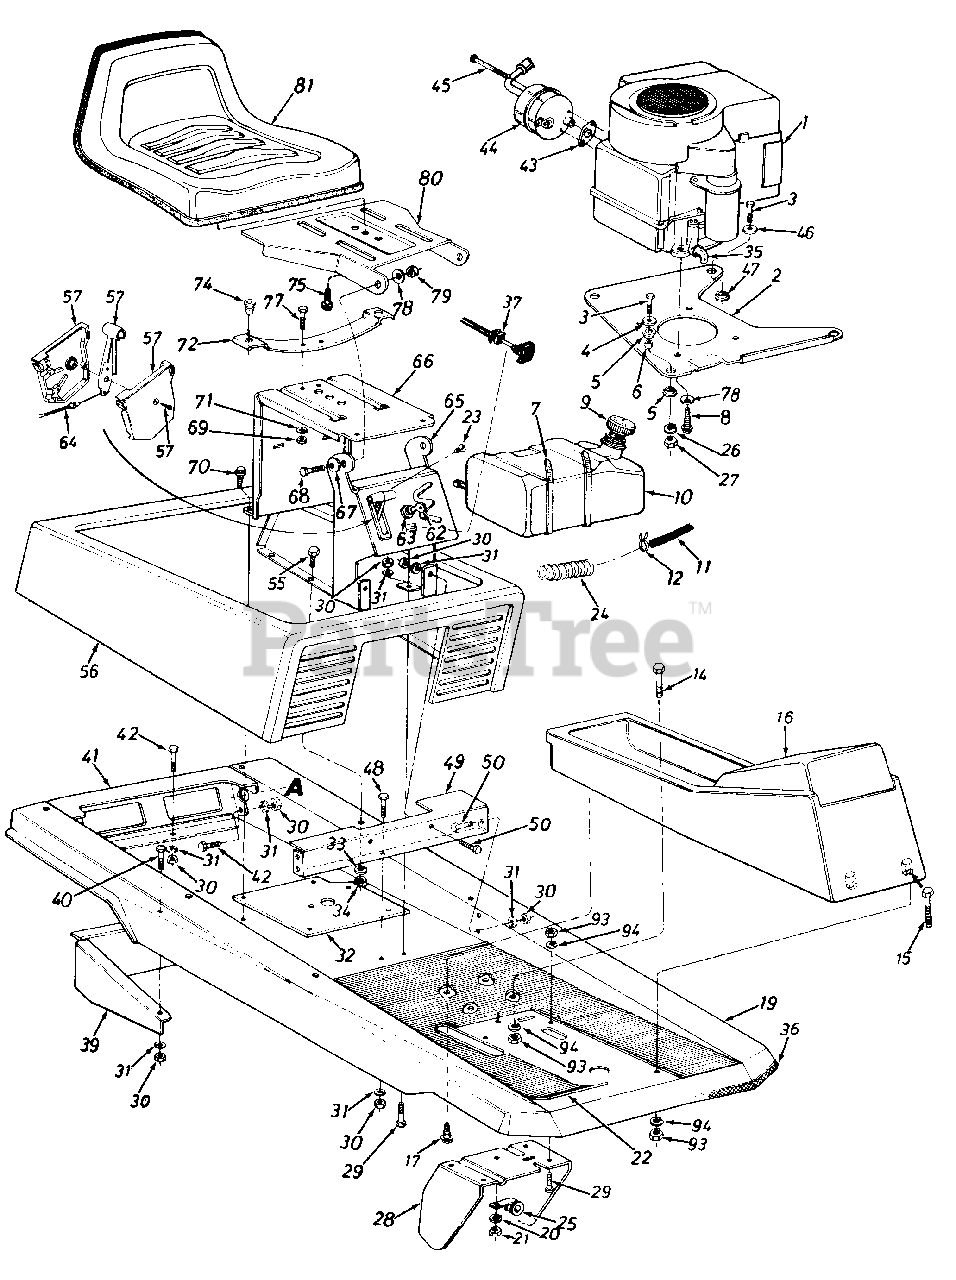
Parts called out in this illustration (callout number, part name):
1	Engine
4	Fl-Wash. .330" I.D. x 1.125" O.D.
5	Engine Mounting Grommet
6	Spacer .315" I.D. x .50" O.D. x.520" Lg.
7	Cable Tie 30.6 Lg.
8	Hex Wash. Hd. Self-Tap Scr. 3/8-16 x 1.25" Lg.
9	Gas Gauge
10	Fuel Tank
11	Gas Line 26 Inches
12	Hose Clamp .406" Dia.
14	Hex Bolt 5/16-18 x 1.75" Lg.
15	Hex Bolt 5/16-18 x 2.0" Lg.
16	Front Console
17	Plastite Scr. 5/16 x 1.25" Lg.
19	Main Frame
20	L-Wash. 5/16" I.D.
21	Hex Nut 5/16-18 Thd.
22	Floor Mat
23	Truss Mach. AB-Tap Scr. #10 x .50" Lg.
24	Convoluted Conduit
25	Clamp
26	L-Wash. 5/16" I.D.
27	Hex Nut 5/16-24 Thd.
28	Clutch-Brake Pedal Ass'y.
29	Hex Bolt 5/16-18 x .75" Lg
30	Hex Nut 5/16-18 Thd.
31	L-Wash. 5/16" I.D.
32	Mounting Brkt. Variable Speed Pulley
33	L-Wash. 1/4" I.D.
34	Hex Nut 1/4-20 Thd.
35	90ø Elbow Male To Female
36	Trim Strip 18" Lg.
37	Choke Control
43	Exhaust Gasket
44	Muffler Ass'y.
45	Shld. Bolt
46	Fl-Wash. .33" I.D. x 1.25" O.D.
47	Flange Wash. .32" I.D. x .75" O.D.
48	Hex Bolt 5/16-18 x .75" Lg.
49	Seat Support & Frame Brkt.
50	Hex Bolt 5/16-18 x .75 Lg.
55	Hex Bolt 1/4-20 x .50" Lg.
56	Engine Cover Ass'y.
57	Throttle Control Box Ass'y.
62	Ignition Key
63	Ignition Switch
64	Throttle Control Wire
68	Hex Bolt 5/16-18 x .75" Lg.
69	Hex Nut 5/16-18 Thd.
70	Hex Self-Tap Scr. 5/16-18 x .75" Lg.
71	L-Wash. 5/16" I.D.
72	Seat Spring
74	Grommet
75	Hex Wash. Hd. Tap Scr. 3/8-16 x 3/4" Lg.
77	Hex Bolt 5/16-18 x .75" Lg.
78	Bell-Wash. .345" I.D. x .88" O.D.
79	Hex Cent. L-Nut 5/16-18 Thd.
80	Seat Pivot Bracket
81	Seat Ass'y. Comp.
93	Hex Nut 5/16-18 Thd.
94	L-Wash. 5/16" I.D.
